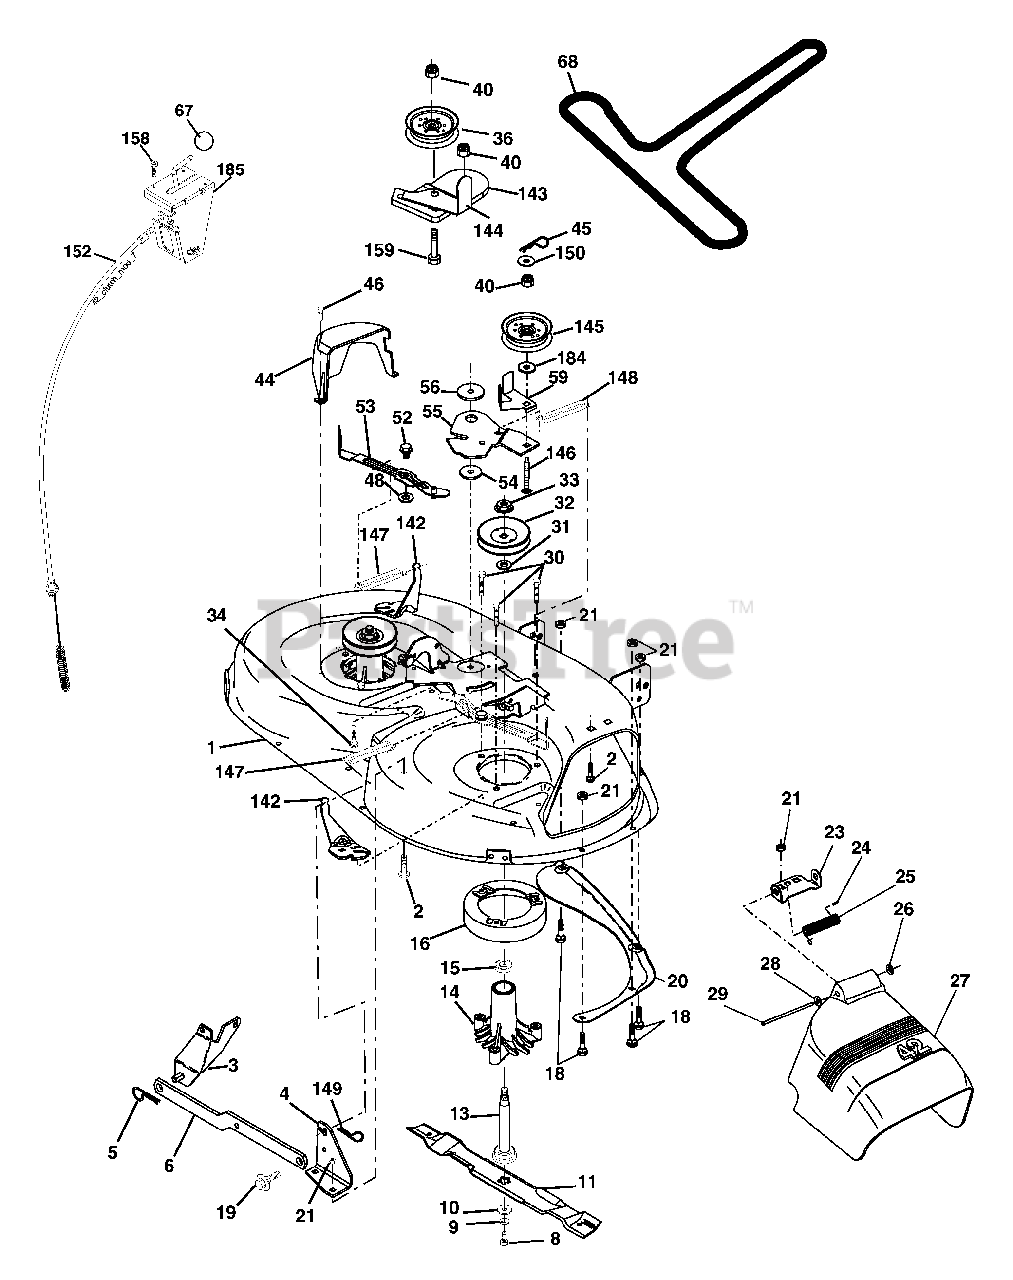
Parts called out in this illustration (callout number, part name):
1	Mower Deck Assembly, 42"
2	Bolt
3	Bracket Asm Fr. Sway Bar 3/42
4	Bracket Asm Deck 42" Sway Bar
5	Retainer Spring
6	Bar Sway Deck
8	Bolt 3/8-24 x 25 Gr. 8 patched
9	Washer, Lock
10	Washer, Hardened
11	Blade, 42" Mulching Std
11	Blade, 42" Mulching Premium
11	Blade, 42" Hi-Lift
13	Shaft Assembly, Mandrel, Vented
14	Housing, Mandrel, Vented
15	Bearing, Ball, Mandrel
16	Stripper, Mandrel Deck
18	Bolt, Carriage 5/16-18 x 5/8
19	Bolt, Shoulder
20	Baffle, Vortex
21	Nut
23	Bracket, Deflector Mower 42"
24	Cap, Sleeve 80 x 112 Blk Mower
25	Spring, Torsion, Deflector 2 52
26	Nut, Push Phos & Oil
27	Shield, Deflector 42" Blk
28	Washer 11/32 x 5/8 x 16 Ga.
29	Rod, Hinge 42" 6 75 W/G
30	Screw Thdrol Washer Head
31	Washer, Spacer Mower Vented
32	Pulley, Mandrel
33	Nut, Toplock 9/16 Flange
34	Bolt
36	Pulley, Idler, Flat
37	Washer 13/32 x 13/16 x 16 Ga.
44	Guard, Mandrel, LH
45	Retainer
46	Screw, Thdrol 1/4-20 x 5/8 T
48	Washer, Hardened
52	Bolt, Shoulder 5/16-18 unc
53	Arm Assembly, Pad, Brake
54	Washer, Hardened
55	Arm, Idler
56	Spacer, Retainer
59	Guard TUV Idler
67	Knob
68	V-Belt, 42" Mower
142	Arm Spring Brake Mower
143	Bracket Arm Idler 42"
144	Keeper Belt 42" Clutch Cable
145	Pulley Idler Flat
146	Bolt Carriage Idler
147	Spring Extension
148	Spring Return Idler
149	Retainer Spring Yellow
150	Washer 9/32 x 3/4 x 10 Ga.
152	Clutch Cable 42"
158	Screw Hex Thd Cut 1/4-20 x 1/2
159	Bolt Rdhd Sqn 3/8-16 unc x 1-3/4
184	Washer 13/32 x 7/8 x 10 Ga.
185	Head Asm Cable Clutch
